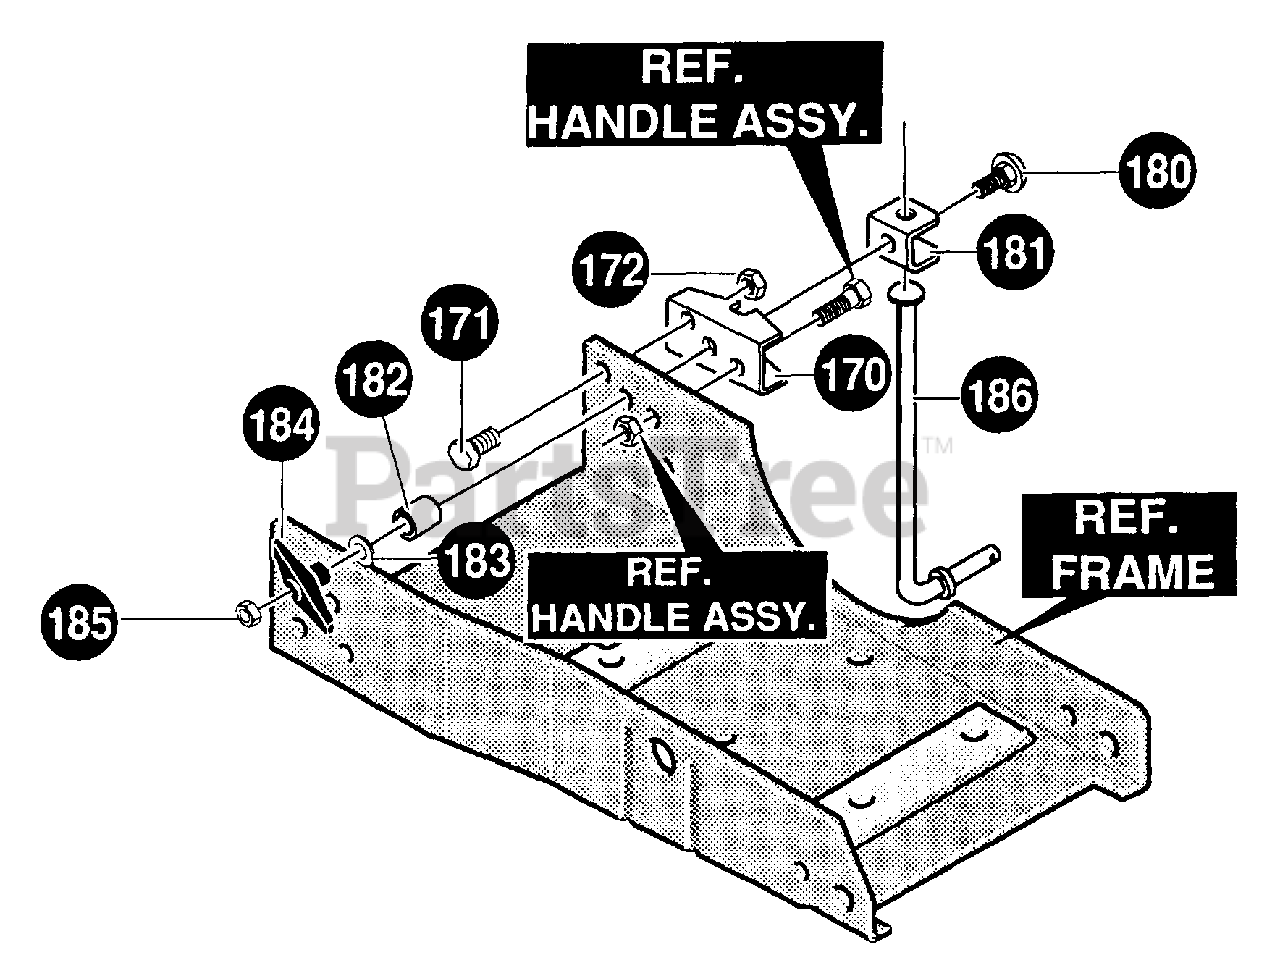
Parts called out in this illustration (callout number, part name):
170	BRKT, CURB HOP MNT
171	SCREW, 5/16-18X .75
172	NUT, 5/16-18 REGHEXCTRLK
180	BOLT, 5/16-18X2.00
182	SPACER, SLEV .356X.63X1.01
183	WASHER, FLAT .344X.69X.065
184	KNOB, T W/516/18 NUT
185	NUT, 5/16-18 REGHEX
186	ROD, WHEEL SUPPORT
